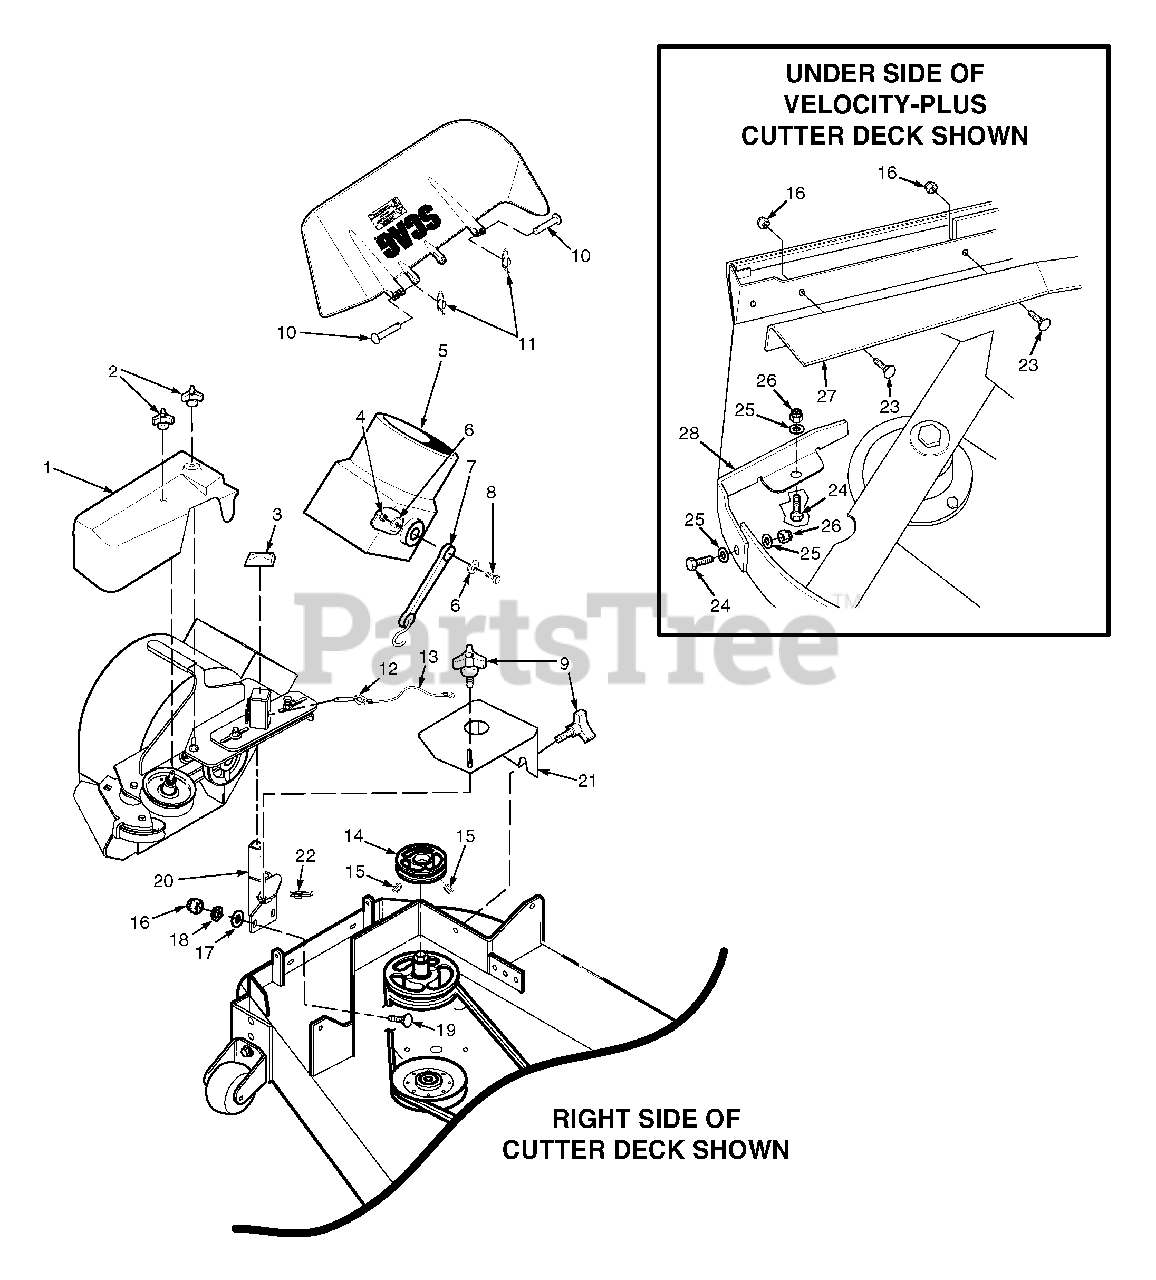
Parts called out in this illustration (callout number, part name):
1	Belt Cover, GC-STC
2	Wingnut, Plastic 3/8" Small
3	Cap, Square Vinyl
4	Nut, Elastic Stop 1/4-20
5	Adapter, Blower GC-STC,
6	Flatwasher, 1/4-.312 x .750 x .065
7	Rubber Strap 7-3/4"
8	Bolt, Hex Head 1/4-20 x 1-1/4"
9	Knob W/Stud, 3/8-16 x 1-1/4"
10	Clevis Pin, 5/16 x 1-1/2"
11	Pin, Rue Cotter 5/16 Dia.
12	Pin, Ring 1/2 x 2-1/4"
13	Lanyard
14	Pulley, 4.0" Dia. 1.125 Bore
15	Setscrew, 5/16-18 x 3/8"
16	Nut, Elastic Stop 3/8-16
17	Lockwasher, 3/8"
18	Flatwasher, 3/8-.391 x .938 x .105
19	Bolt, Carr. 3/8-16 x 1-1/4" Grade 5
20	Mounting Post Weldment, Blower
21	Belt Cover, GC-STC-48V
23	Bolt, Carriage 3/8-16 x 1"
24	Bolt, Hex Head 5/16-18 x 1"
25	Flatwasher, 5/16-.375 x .875 x .083
26	Nut, Elastic Stop 5/16-18
27	Baffle, Front 48" Deck
28	Baffle, Turbo 48" Deck
